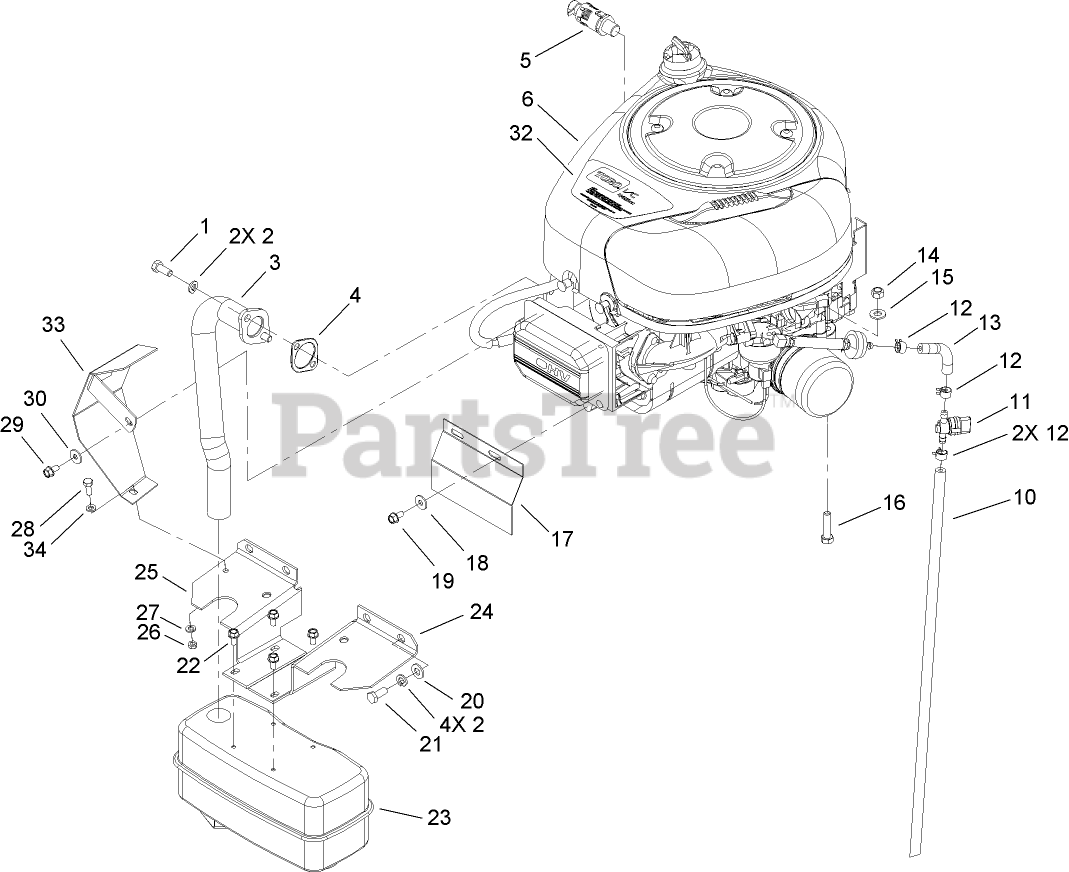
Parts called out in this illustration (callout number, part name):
1	SCREW-HH
3	TUBE-EXHAUST
4	GASKET-EXHAUST
5	VALVE-OIL DRAIN
6	Loose Parts Package
10	LINE-FUEL
11	VALVE-TANK, FUEL
12	CLAMP-LINE, FUEL
13	LINE-FUEL
14	NUT-LOCK, NI
15	WASHER-PLAIN
16	SCREW-HH
17	COVER-FRONT
18	WASHER-FLAT
20	WASHER-PLAIN
21	SCREW-HH
23	MUFFLER
24	GUARD-MUFFLER, LH
25	GUARD-MUFFLER, RH
26	NUT-HEX
27	WASHER-SPRING
28	SCREW-HH
30	WASHER-FLAT
32	DECAL-ENGINE, I/C
33	Cover-Manifold, Exhaust
34	WASHER-FLAT
